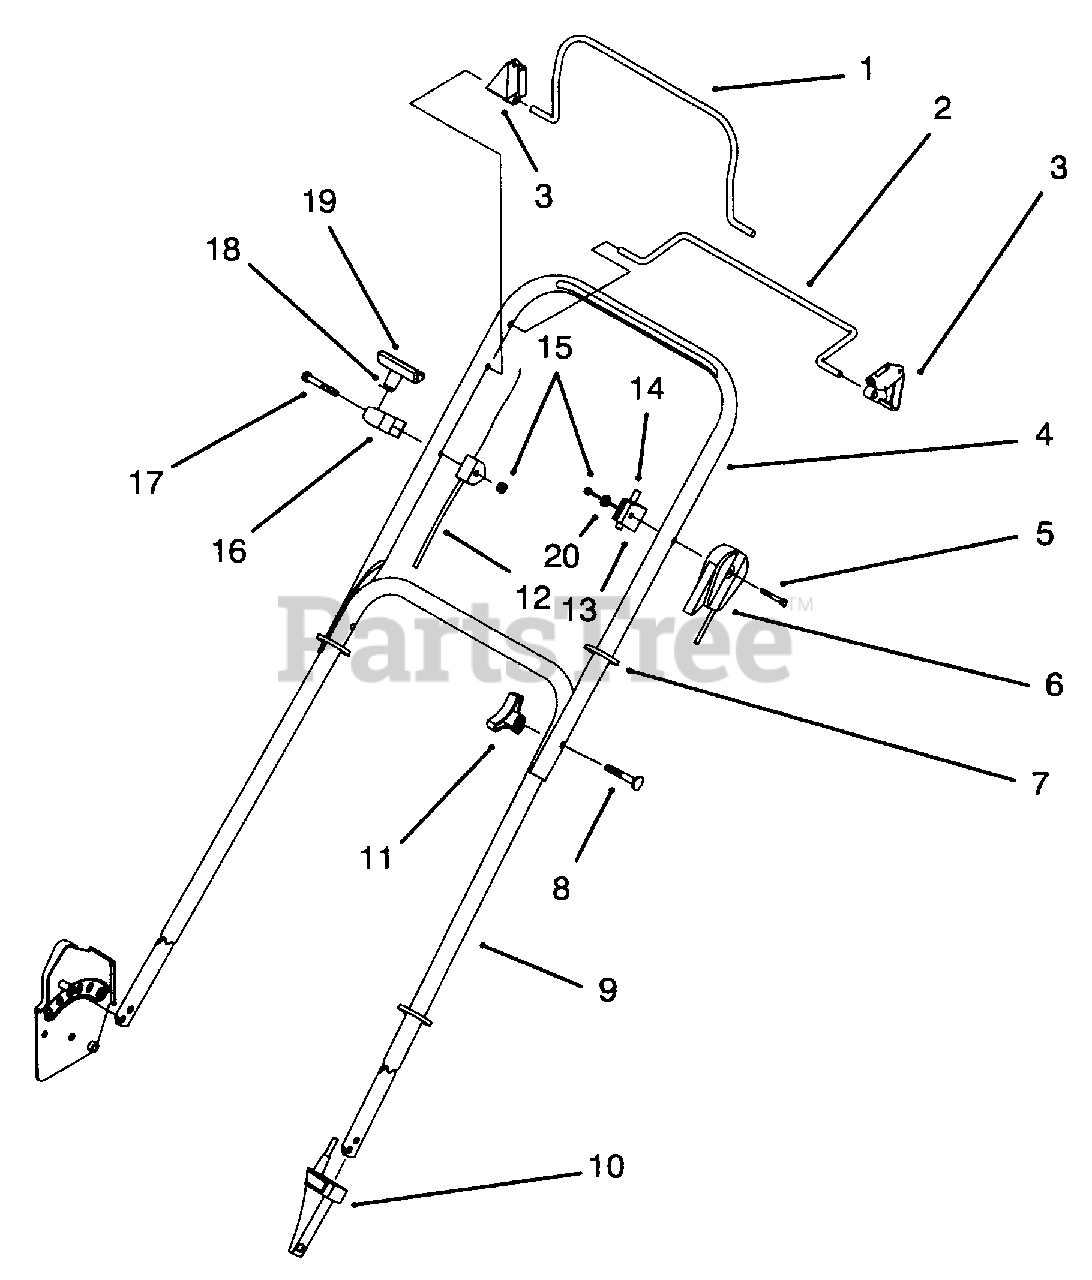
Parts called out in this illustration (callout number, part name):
1	Bail-Flywheel Brake
2	Bail-SP Control (Model No. 10312 Only)
3	Stop-Pivot (Qt'y (1) Model No. 10211 Only)
4	Handle-Upper
5	Screw-Hex Hd. Cap (Model No. 10211 Only)
6	Cable-Throttle
7	Tie-Cable (Qt'y (1) Model No. 10211 Only)
8	Screw-Handle
9	Handle-Lower
10	Anchor-Cable SP Lower (Model No. 10312 Only)
11	Knob
12	Cable-Flywheel Brake
13	Anchor-Cable SP Upper (Model No. 10312 Only)
14	Cable-Traction (Model No. 10312 Only)
15	Nut-Lock
16	Guide-Rope
17	Screw-Hex Hd. Cap
18	Handle-Starter
19	Clip-Rope Insert
20	Washer (Model No. 10211 Only)
